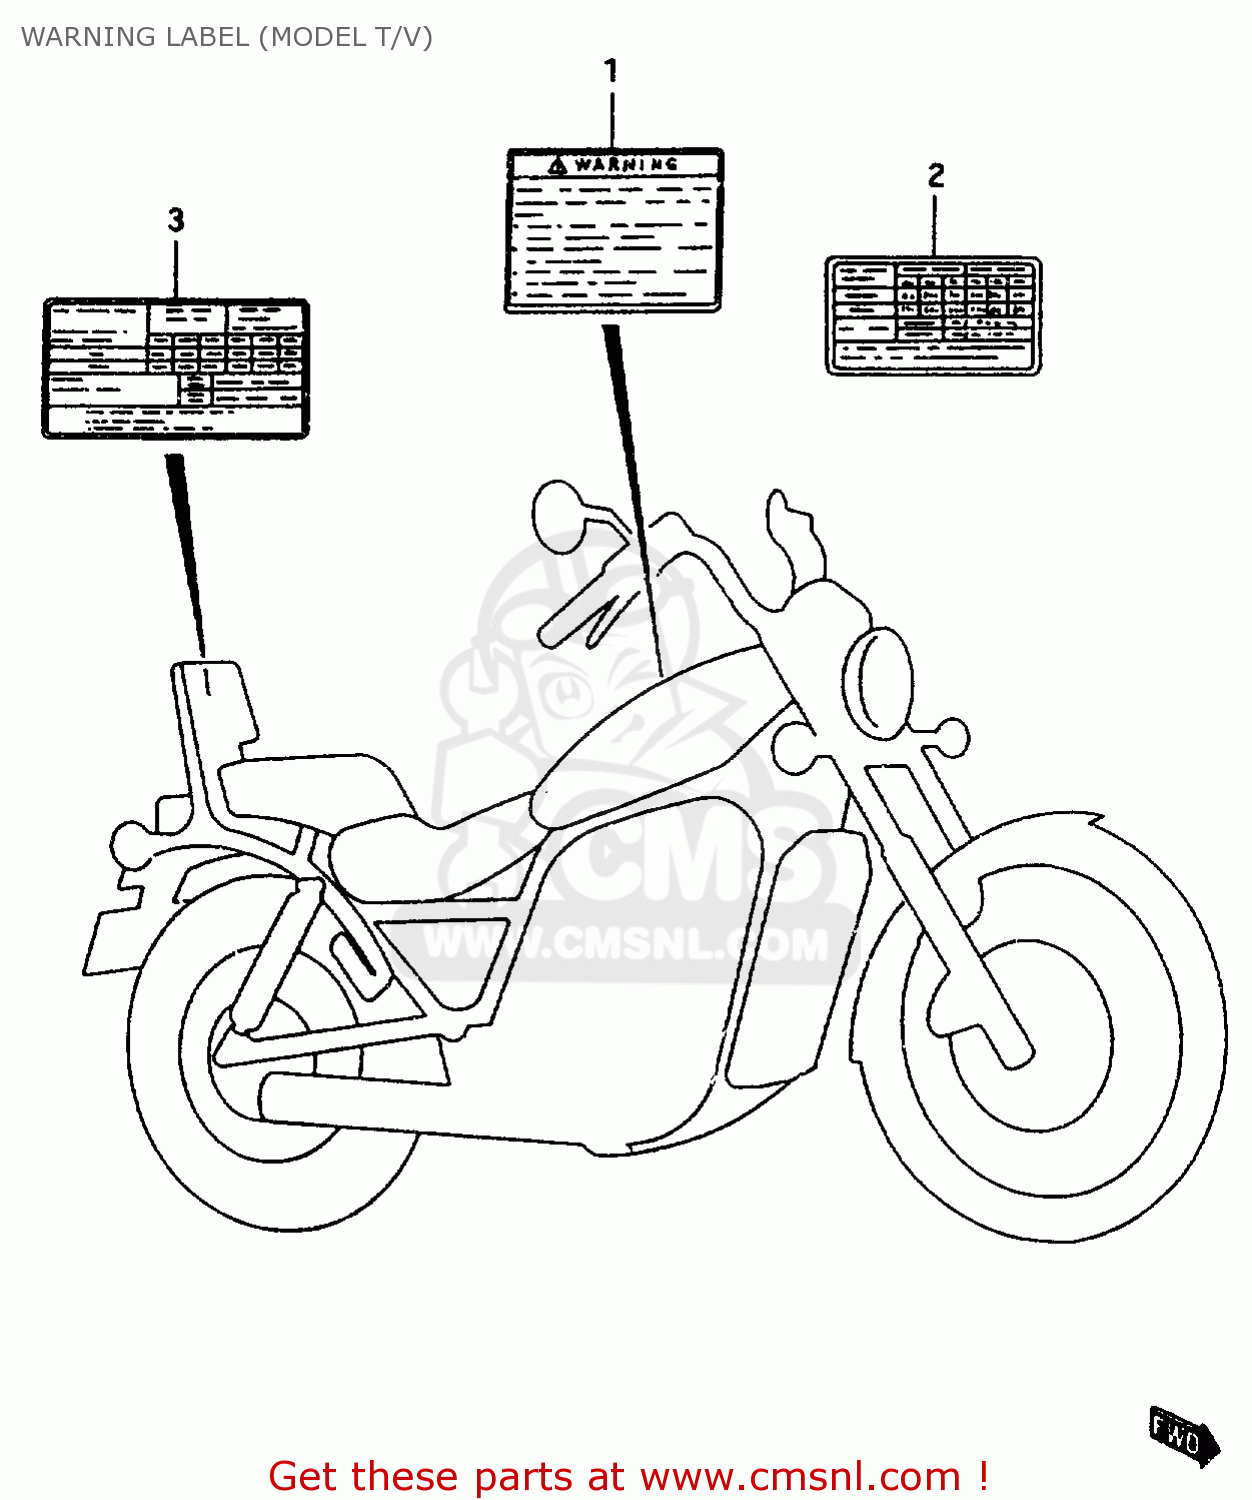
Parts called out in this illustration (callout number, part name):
1	LABEL,WARNING
2	LABEL,CAUTION
3	LABEL, AIR PRESSURE
4	VS600/800GL O.
5	MANUAL, OWNERS
